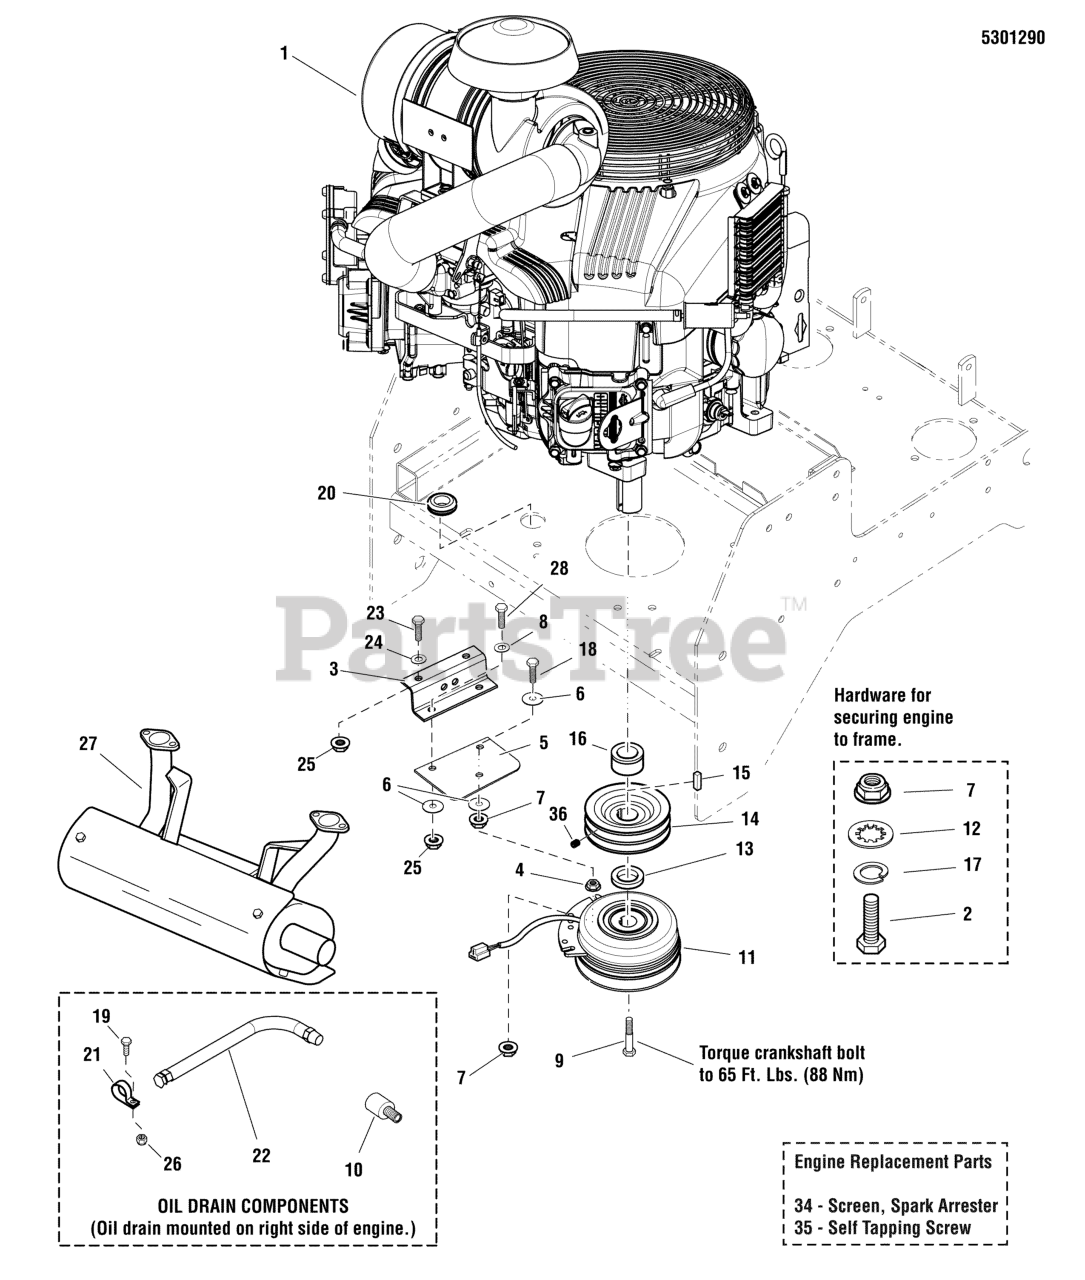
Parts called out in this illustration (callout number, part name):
1	ENGINE, BRIGGS AND STRATTON
2	BOLT, 5/16-18 X 1-3/4 GD5 YZ
3	ANCHOR, CLUTCH - BLK
4	NUT, 5/16-18 HEX SERRATED FLANGE (LARGE)
5	CLUTCH ANCHOR PAD
6	WASHER, .34 X 1.25 X 10 GA
7	NUT, 5/16-18 HEX NYLOCK FLANGE
8	WASHER, 5/16" SAE
9	BOLT, CRANKSHAFT, 7/16X2-1/2
10	METRIC ADAPTER, M14-1.5" TO 3/8 NPTF
11	* CLUTCH, 5218-134, WARNER
12	WASHER, 5/16 INT. TOOTH LOCK
13	SPACER, 1.13 X 1.75 X .50
14	PULLEY, CRANKSHAFT, 1.126 ID X 4.75 OD
15	KEY, 1/4 SQ X 1
16	SPACER, 1.13 X 1.75 X 1.09, PM
17	WASHER, 5/16 LOCK CZ
18	BOLT, 5/16-18 X 2-1/4 TFL, GD5 YZ
19	BOLT, 1/4-20 X 1" GD5 CZ
20	GROMMET, 7/8
21	CLAMP, VINYL INSULATED
22	HOSE, OIL DRAIN
23	BOLT, 3/8-16 X 1" GD5 CZ
24	WASHER, 3/8 SAE
25	NUT, 3/8-16 HEX NYLOCK FLANGE
26	NUT, 1/4-20 HEX NYLOCK FLANGE
27	MUFFLER, ASSY, SERVICE PART
28	BOLT, 5/16-18 X 1 GD5 YZ
36	SET SCREW, 5/16-18 X 3/8, KNURL, W/PATCH
